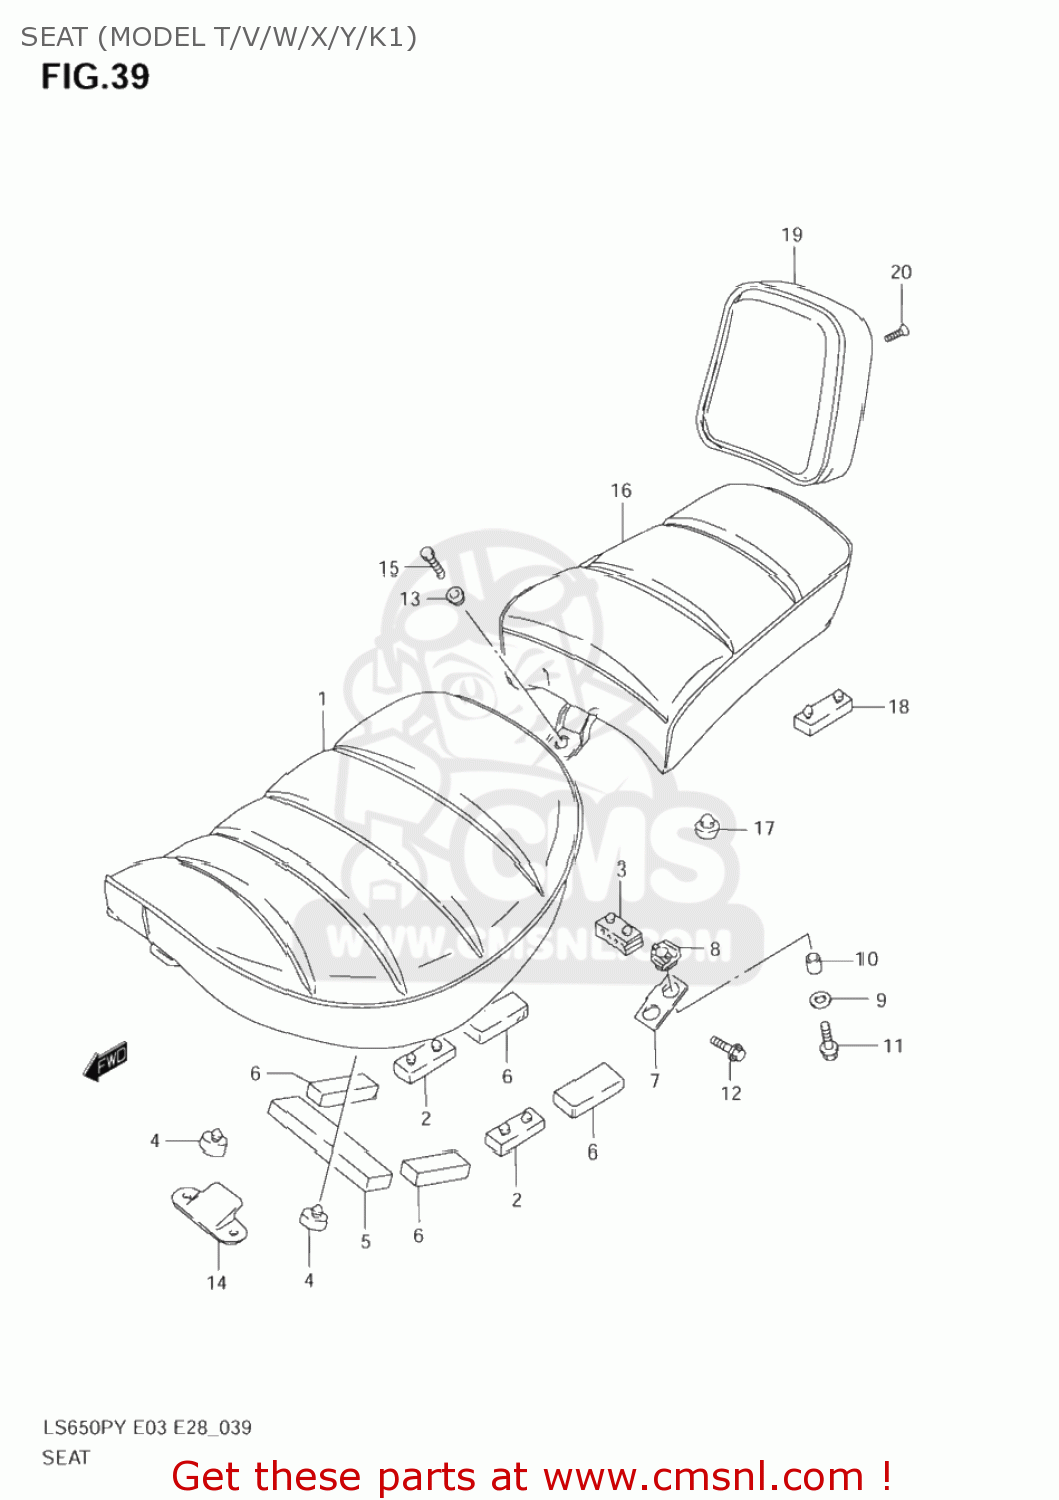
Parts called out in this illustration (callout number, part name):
1	SEAT SET
2	CUSHION,SEAT
3	CUSHION,SEAT(40X20X15)
4	CUSHION(11.5X22X20)
5	CUSHION,CTR FR
6	CUSHION,CTR SIDE
7	BRACKET,SEAT RR
8	CUSHION,SEAT RR BRACKET
9	WASHER(6.5X20X1.6)
10	COLLAR,SEAT(TS-5A1-02273)
11	BOLT
12	BOLT
13	WASHER
14	PLATE,SEAT HOOK FR
15	BOLT
16	SEAT SET,PILLION
17	CUSHION,SEAT
18	CUSHION,SEAT
19	PAD ASSY,SEAT
20	SCREW,SUNVISOR
